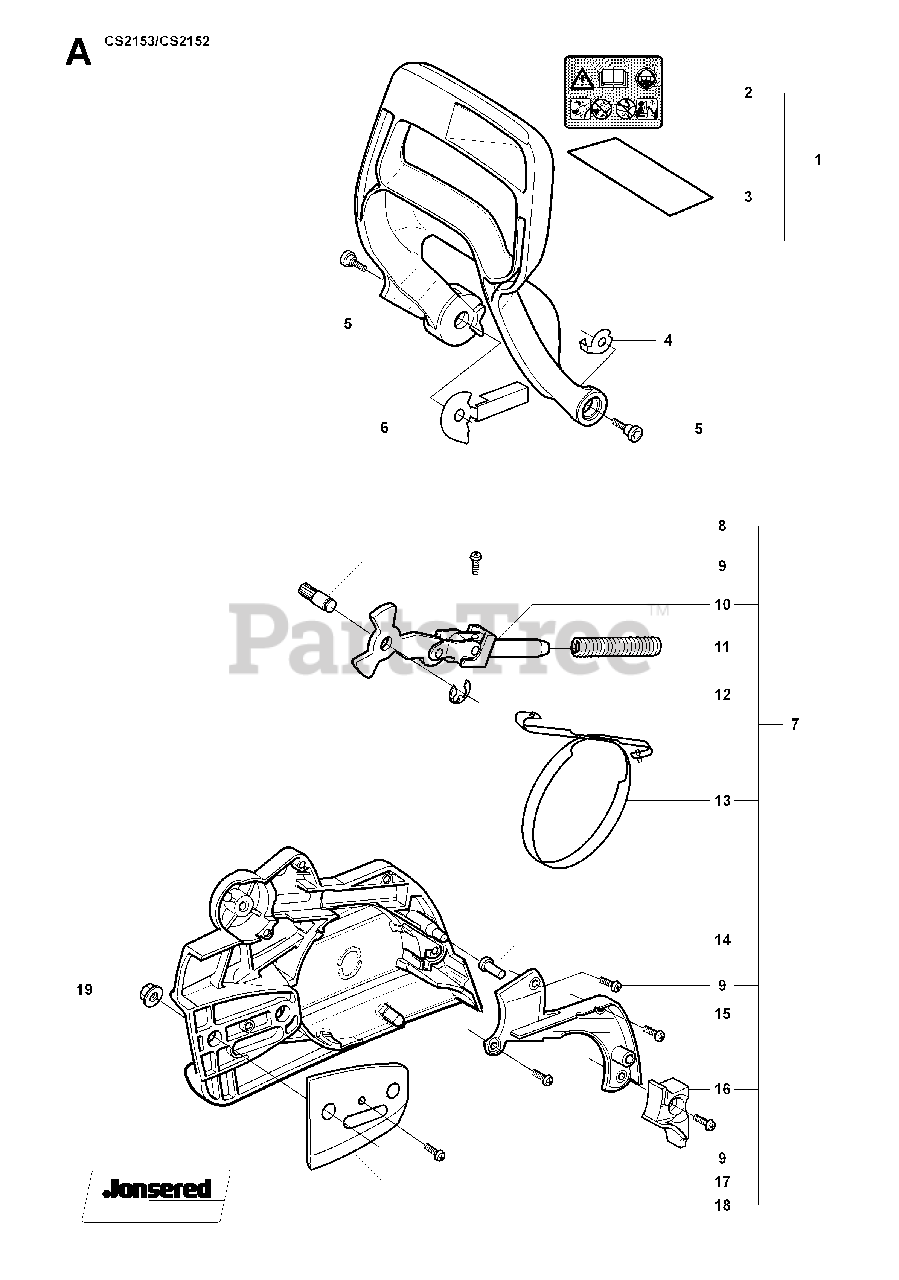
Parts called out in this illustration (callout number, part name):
1	HAND GUARD
3	PROTECTOR
5	SCREW
6	PROTECTOR
7	CHAIN BRAKE
13	BRAKE BAND
16	PROTECTOR
19	NUT M8 FLANGE
